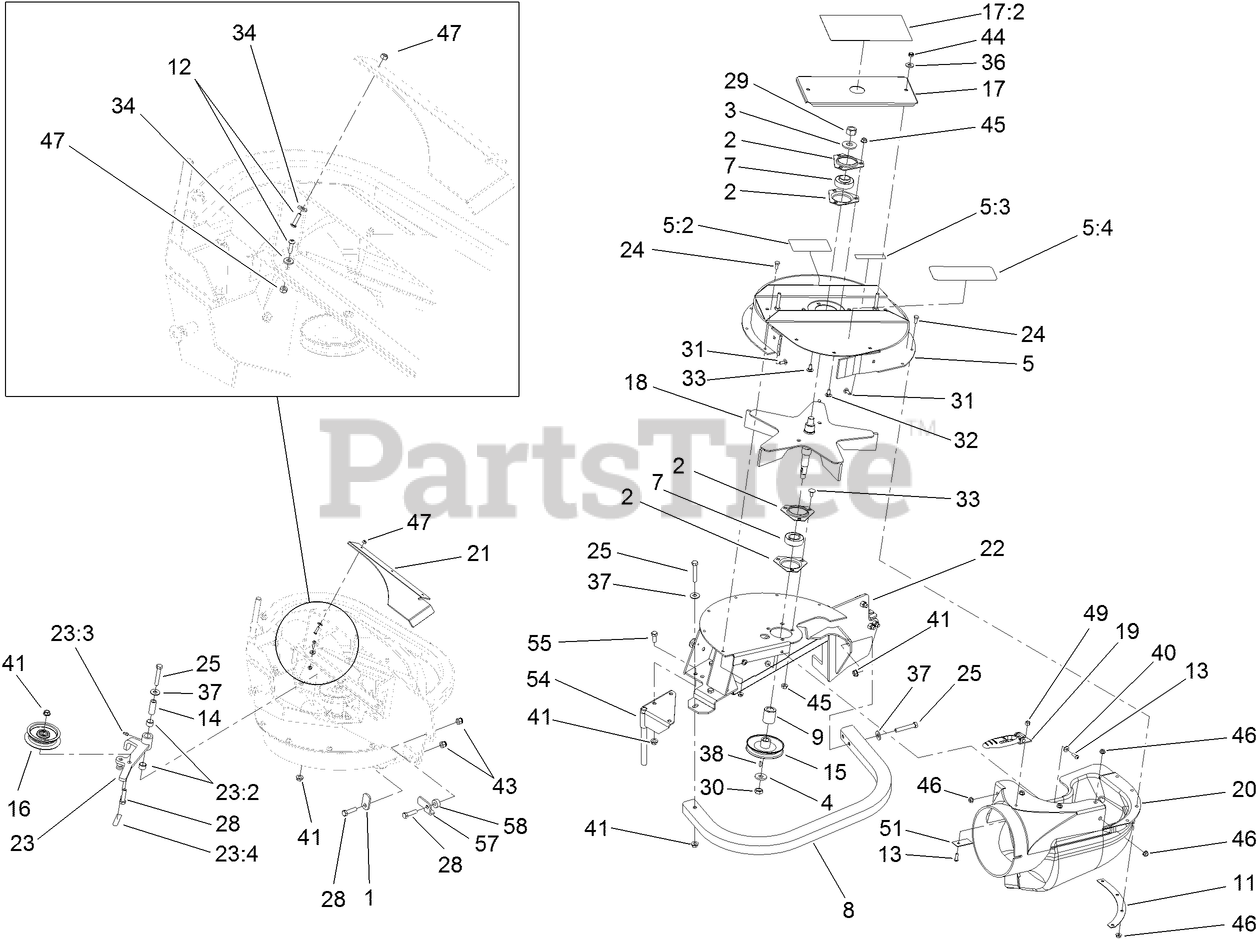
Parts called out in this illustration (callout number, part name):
1	LATCH-CATCHER, GRASS
2	HOUSING-FLANGE
3	WASHER-SPRING
4	WASHER-FLAT
5	UPPER HOUSING ASM
5:2	DECAL-WARNING
5:3	DECAL-COVER, MISSING
7	BEARING
9	SPACER
11	PLATE-BACKING, BLOWER
12	SCREW-HSBH
13	SCREW-HSBH
14	BUSHING
15	SHEAVE
16	IDLER-FLAT
17	COVER-BEARING
17:2	DECAL-WARNING, BLOWER
18	IMPELLER
19	LATCH-RUBBER
20	CHUTE-BLOWER
21	PLATE-BOTTOM
22	MOUNT-BLOWER
23	IDLER ARM ASM
23:2	BUSHING
23:3	FITTING-GREASE
23:4	DECAL-WARNING
24	SCREW-HH
25	SCREW-HH
28	SCREW-HH
29	NUT-HEX
30	NUT-LOCK, NI
31	BOLT-CARR
32	SCREW-CARR
33	SCREW-CARR
34	WASHER-FLAT
36	WASHER-FLAT
37	WASHER-FLAT
38	KEY-WOODRUFF
40	WASHER-FLAT
41	NUT-HHF, WHIZ
43	NUT-LOCK, NI
44	NUT-LOCK, NI
45	NUT-HF
46	NUT-HF
47	NUT-LOCK, NI
49	NUT-LOCK, NI
51	PLATE-BACKING
54	PIN-MOUNT
55	SCREW-HH
57	LATCH-STOP
58	SPACER
